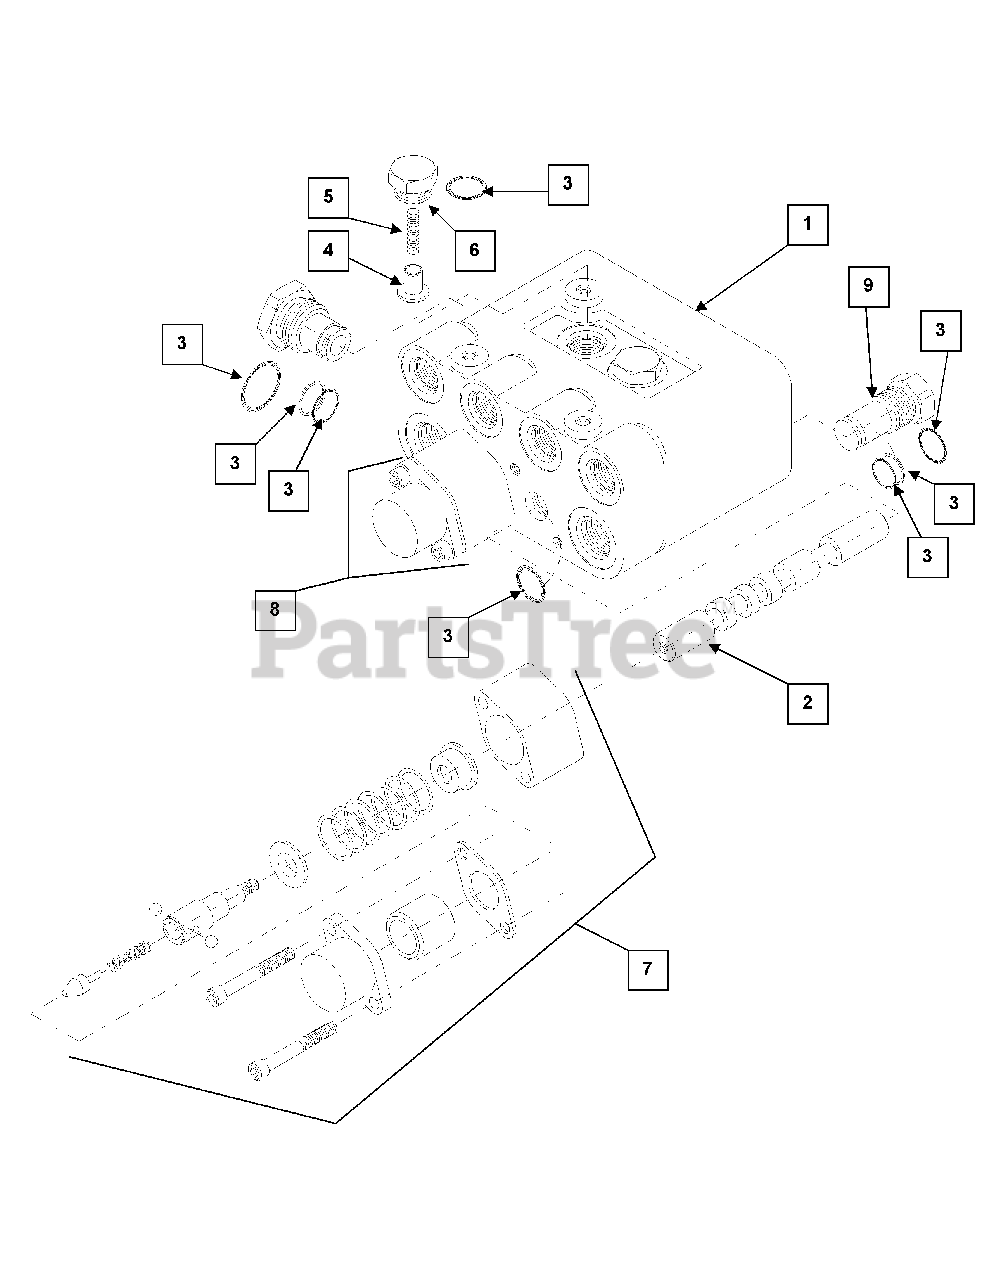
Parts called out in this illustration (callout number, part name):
1	Valve Body
2	Spool
4	Load Check Poppet
5	Load Check Spring
6	Load Check Plug
7	Float Detent Spool Repair Kit
8	Regen Spool Repair Kit
9	Relief Valve Cartridge
